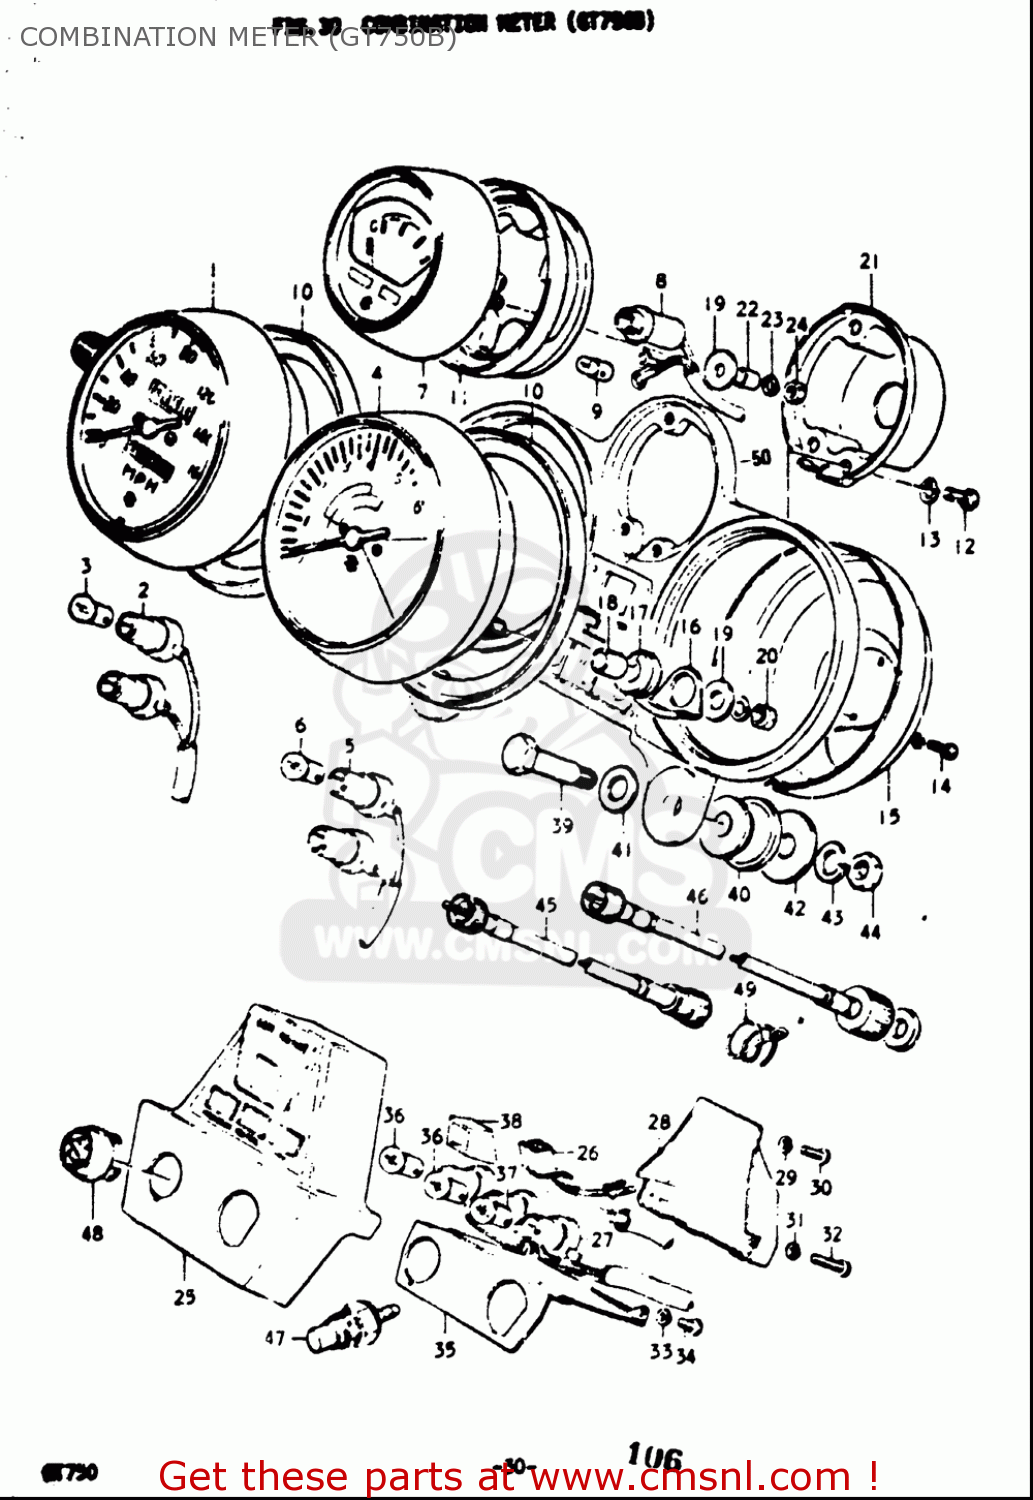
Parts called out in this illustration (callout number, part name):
3	BULB(12V3.4W,STANLEY,A72A)
6	BULB(12V3.4W,STANLEY,A72A)
7	THERMOMETER ASSEMBLY
9	BULB(12V2W,STANLEY,A1272J)
10	CUSHION,SPEEDOMETER
13	WASHER,LOCK
14	SCREW
15	PLATE,UNDER
18	SPACER,METER
19	WASHER(5.5X16X1.2)
20	NUT
23	WASHER,LOCK
24	NUT
25	CASE,PILOT BULB
29	WASHER,LOCK
30	SCREW
31	WASHER,LOCK
32	SCREW
33	WASHER,LOCK
34	SCREW 4X6
35	BRACKET (BB)
36	BULB(12V3.4W,STANLEY,A72A)
37	BULB(12V1.7W,A71A)
39	BOLT(8X39.2)
40	CUSHION,METER BRACKET
41	WASHER
42	WASHER(8.5X28X1.6)
43	WASHER,LOCK
44	NUT
45	CABLE ASSY,SPEEDOMETER
46	CABLE ASSY,TACHOMETER
47	GAUGE ASSY,WATER TEMP
48	CAP,SPEED WARNER LAMP HOLE
